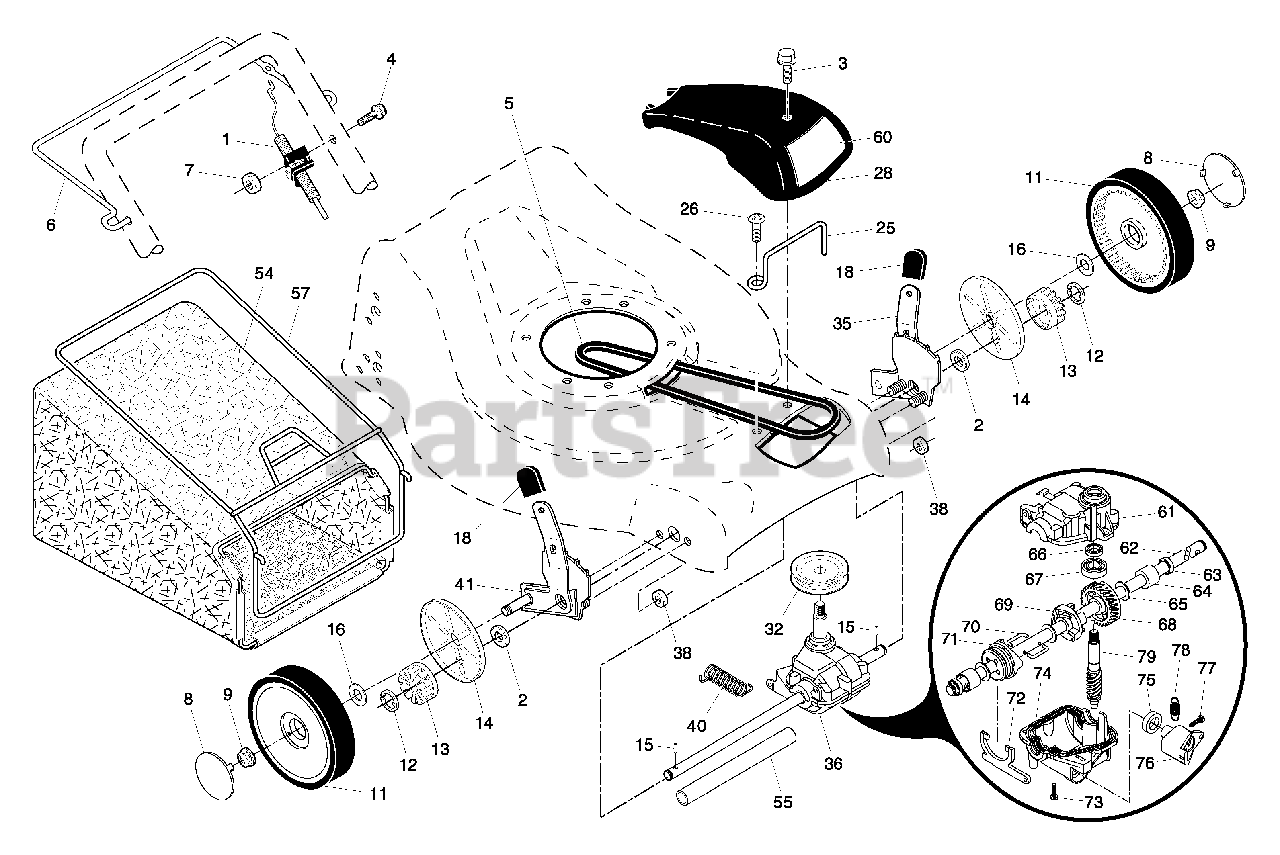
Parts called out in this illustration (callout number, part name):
1	Drive Control Assembly, with Cable
2	Bearing, Wheel Adjuster
3	Pan Head Tapping Screw #10-24 x 2-3/4
4	Hex Washer Head Screw 1/4-20 x 2.12
6	Control Bar, Drive
7	Locknut, Hex #10-24
8	Hubcap
9	Locknut, Hex
11	Wheel & Tire Assembly
13	Gear, Pinion
14	Dust Cover
15	Pawl, Drive
16	Washer 1/2 x 1-1/2 x .134
18	Selector Knob
25	Belt Keeper
26	Screw
28	Drive Cover
32	Drive Pulley
35	Kit, Wheel Adjuster, LH
36	Gearcase Assembly, Complete
38	Locknut, Hex 1/4-20
41	Kit, Wheel Adjuster, RH
54	Grassbag Assembly
55	Driveshaft Cover
57	Frame, Grassbag
60	Decal, Drive Cover
61	Case, Upper
62	Shaft, Output
63	Seal, Output Shaft
66	Seal, Worm Shaft
67	Bearing, Ball
68	Gear, 27 Teeth
69	Fixed Dog Clutch
71	Movable Dog Clutch
73	Screw, Case
74	Case, Lower
75	Seal, Lever
77	Screw, Lever
79	Shaft, Worm
